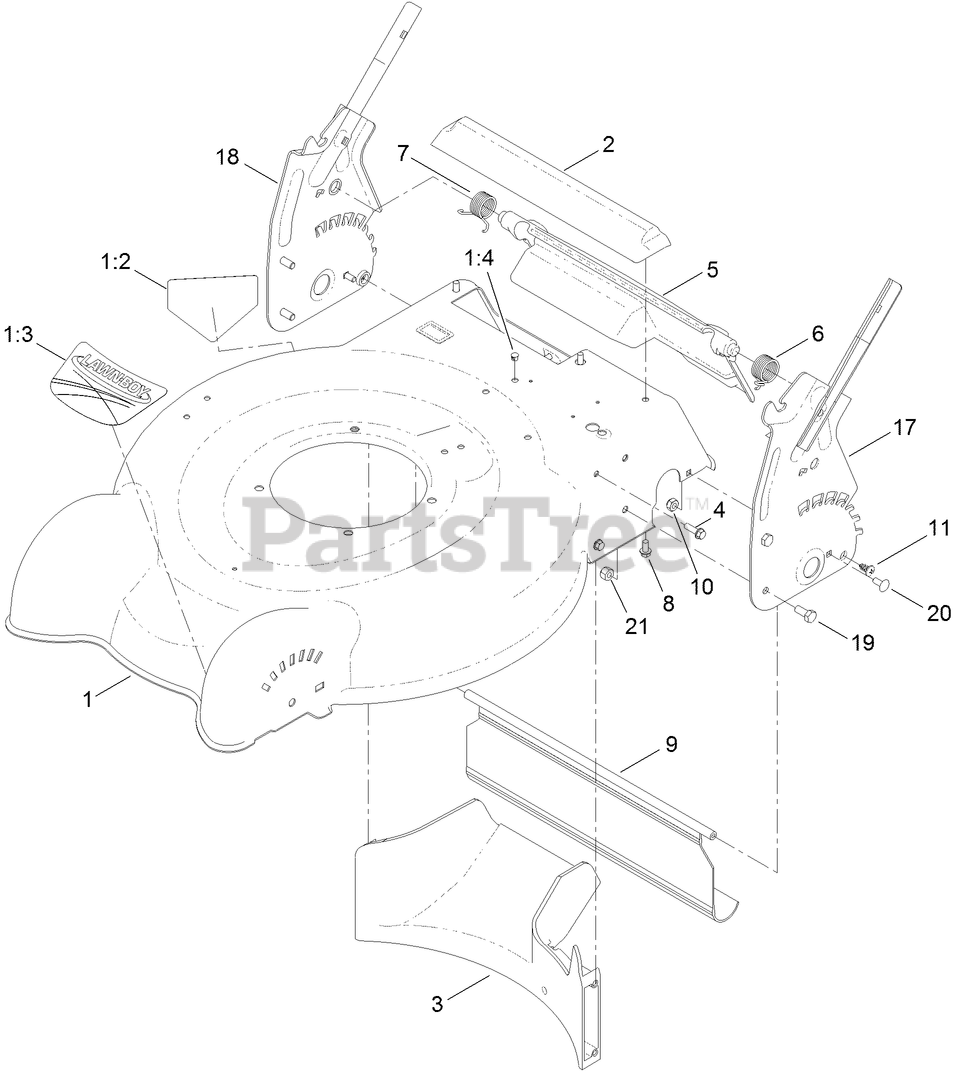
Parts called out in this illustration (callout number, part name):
1	HOUSING ASM
1:2	DECAL-DANGER
1:4	PLUG-DOME
2	CHUTE-REAR
3	BAFFLE-REAR
4	SCREW-HWH
5	REAR DEFLECTOR ASM
6	SPRING-TORSION, LH
7	SPRING-TORSION, RH
8	SCREW-PLASTITE
10	NUT-LOCK, NI
11	SCREW-PTH
19	SCREW-HH
20	SCREW-CARR
21	NUT-LOCK, NI
